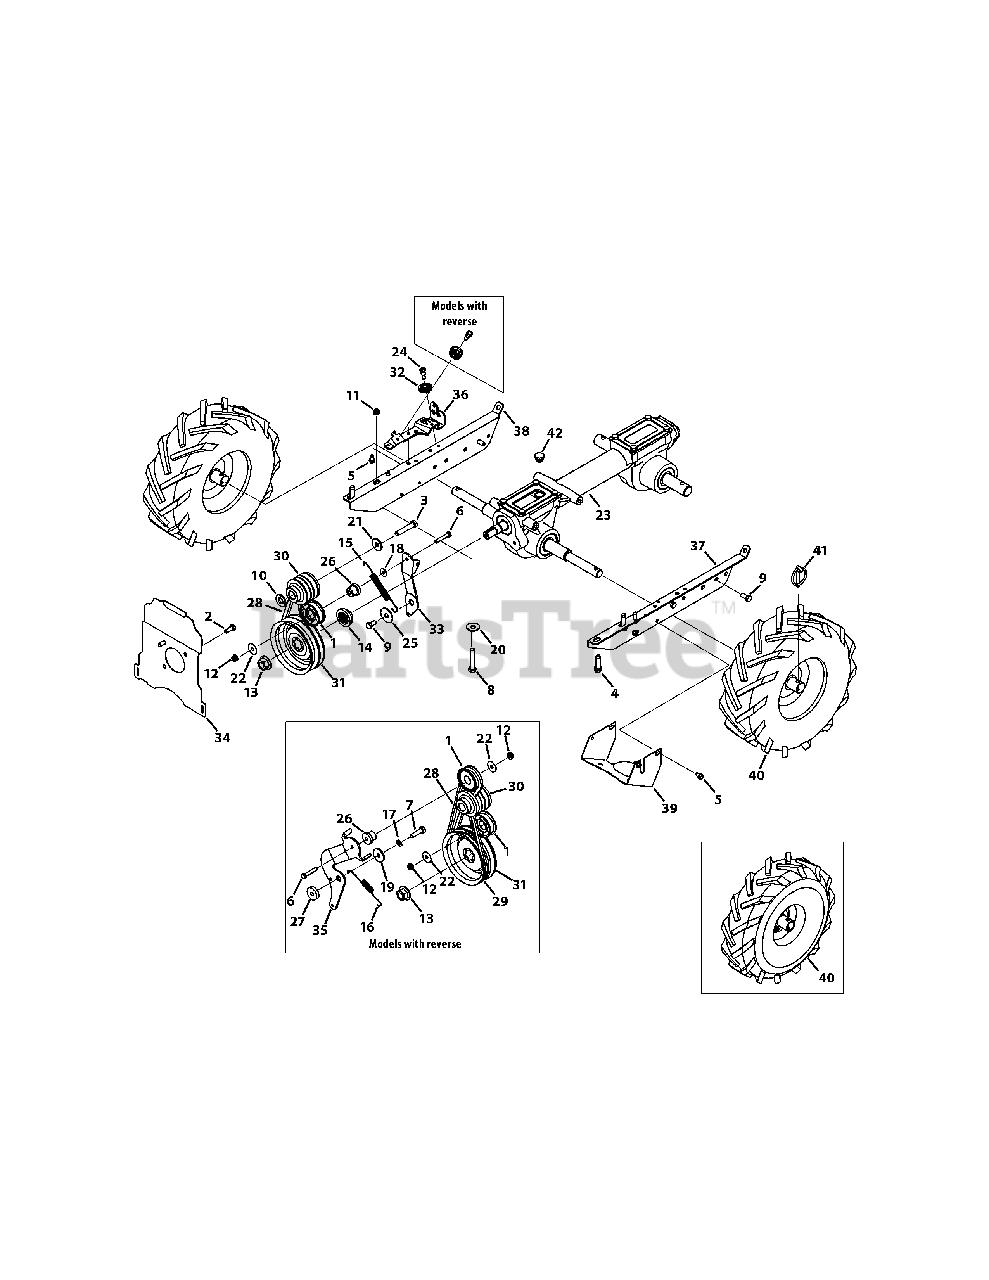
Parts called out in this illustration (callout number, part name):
1	Idler Pulley Assembly, 1.917 OD
2	Hex Head Screw, 5/16-24 x .625
3	Hex Head Screw, 3/8-24 x 2.25, B&S
3	Hex Head Screw, 3/8-24 x 2.00
4	Screw, 3/8-16 x 1.250
5	Screw, 1/4-20 x 0.500
6	Hex Head Screw, 1/4-20 x 1.50
7	Hex Head Screw, 5/16-24 x 1.25
8	Hex Head Screw, 5/16-18 x 1.50, B&S
9	Hex Head Screw, 5/16-18 x .75, Patch
10	Washer, Flat, .760 x 1.50 x .120
11	Flangelock Nut, 5/16-18, B&S
12	Flangelock Nut, 1/4-20
13	Flange Nut, 9/16-18
14	Pulley Hub, 5/8 SPLINE
15	Extension Spring, .480 OD x 5.00 LG
16	Extension Spring, LT5 PTO
17	Washer, Lock, 5/16
18	Washer, Flat, .28 x .74 x .063
19	Washer, Flat, .330 x 1.25 x .120
20	Washer, .396 x 1.140 x .095, B&S
21	Washer, Bell, .396 x 1.140 x .095
22	Washer, Flat, .265 x 1.0 x .030
23	Transmission Assembly
24	Screw, Shoulder, 1/4-28 x .342 x .335
25	Forward Idler Pivot Spacer
26	Spacer, Shoulder, .260 x .785 x .538
27	Reverse Idler Pivot Spacer
28	V Belt, 4L x 25.375 LG
29	V Belt, 3L x 29.125 LG
30	Engine Pulley, 3L & 4L, Honda
31	Transmission Pulley
32	Cable Roller
33	Forward Idler Bracket
34	Cover Mounting Plate
35	Reverse Idler Bracket
36	Pulley Mounting Bracket
37	LH Mount Frame
38	RH Mount Frame
39	Pulley Shield
40	Wheel, 13 x 5 x 6
40	Wheel Assembly, 11 x 4-4
41	Klik Pin, .25 DIA x 1.56
